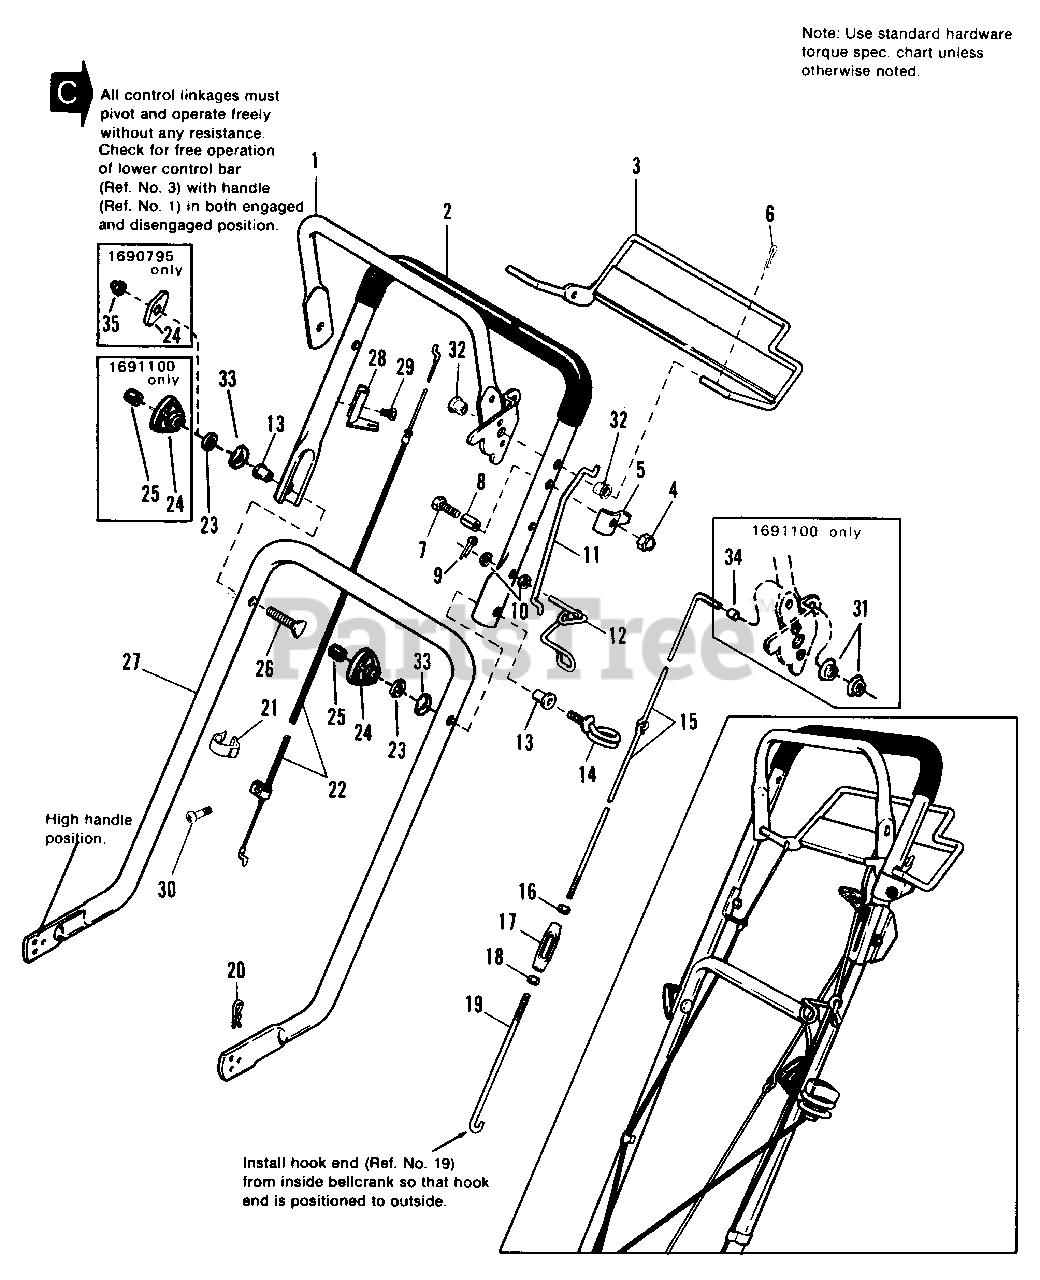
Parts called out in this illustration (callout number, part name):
1	HANDLE ASSY., Self Propelling (1690795 only)
1	HANDLE ASSY., Self-Propelling (1691100 only)
2	HANDLE, Upper, Coated
3	LOWER CONTROL BAR
4	LOCKNUT, Hex, Full, #10-24 (Nylon)
5	STOP, Bail
6	PIN, Cotter, 3/32 x 3/4
7	SCREW, #10-24 x 1-1/2
8	PIN, Roll, 3/8 x 1-1/4
9	COTTER PIN 1/16 x 1/2
9	NUT, Pal, 3/16 (Use if item 12 does not have hole for Cotter Pin)
11	ROD, Rope Stop
12	STOP, Rope
14	ROPE GUIDE ASSY.
15	CLUTCH ROD, Upper (1691100 only)
15	CLUTCH ROD, Upper (1690795 only)
16	NUT,Hex, Full, #10-24, LH Thd
18	NUT, Hex, Full, #10-24, RH Thd
19	CLUTCH ROD, Lower
20	CLIP, Spring
22	CABLE ASSY., Brake
23	WASHER-Shakeproof, 5/16
24	KNOB, Handle (1691100 only)
24	HANDLE, Wing (1690795 only)
25	CAP, Bolt End, Plastic (1691100 only)
26	BOLT, Curved Hd.
27	HANDLE, Lower
28	BRACKET, Cable Mfg.
29	SCREW, Taptite, 1/4-20 x 1/2
30	SCREW, #10-32 x 3/8 Sems
31	NUT, Push, 5/32 (1691100 only)
33	WASHER, Curved, 5/16 (1691100 only)
34	SPACER, Clutch Rod (1691100 only)
35	NUT, Acorn 5/16-18 (1690795 only)
